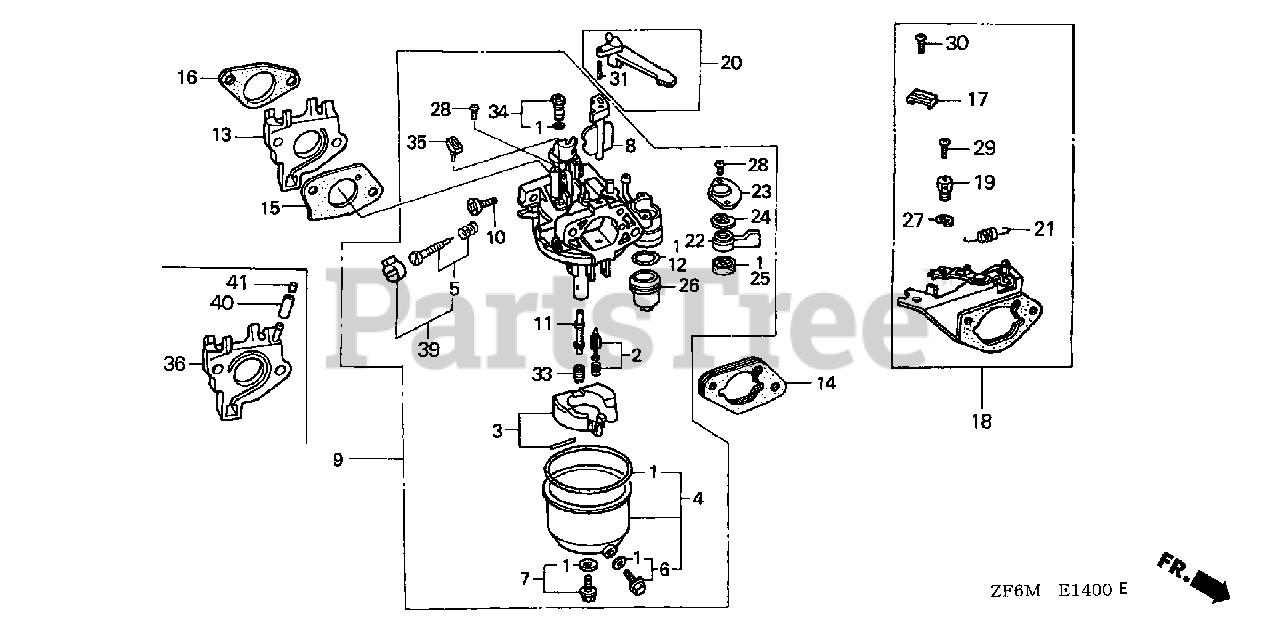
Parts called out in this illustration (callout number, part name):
1	GASKET SET
2	VALVE SET, FLOAT
3	FLOAT SET
4	CHAMBER SET, FLOAT
5	SCREW SET
6	SCREW SET, DRAIN
7	SCREW SET B
8	CHOKE SET
9	CARBURETOR ASSY. (BE85B B)
10	SCREW, THROTTLE STOP
11	NOZZLE, MAIN
12	GASKET, FUEL STRAINER CUP
13	INSULATOR, CARBURETOR
14	SPACER, CARBURETOR
15	GASKET, CARBURETOR
16	GASKET, INSULATOR
20	LEVER, CHOKE (STD)
22	LEVER, VALVE
23	PLATE, LEVER SETTING
24	SPRING, VALVE LEVER
25	GASKET, VALVE
26	CUP, FUEL STRAINER
28	SCREW, PAN (3X6)
31	PIN, SPRING (2X12)
33	JET, MAIN (#88)
33	JET, MAIN (#90)
33	JET, MAIN (#92)
34	JET SET, PILOT (#45)
35	COLLAR, SET
